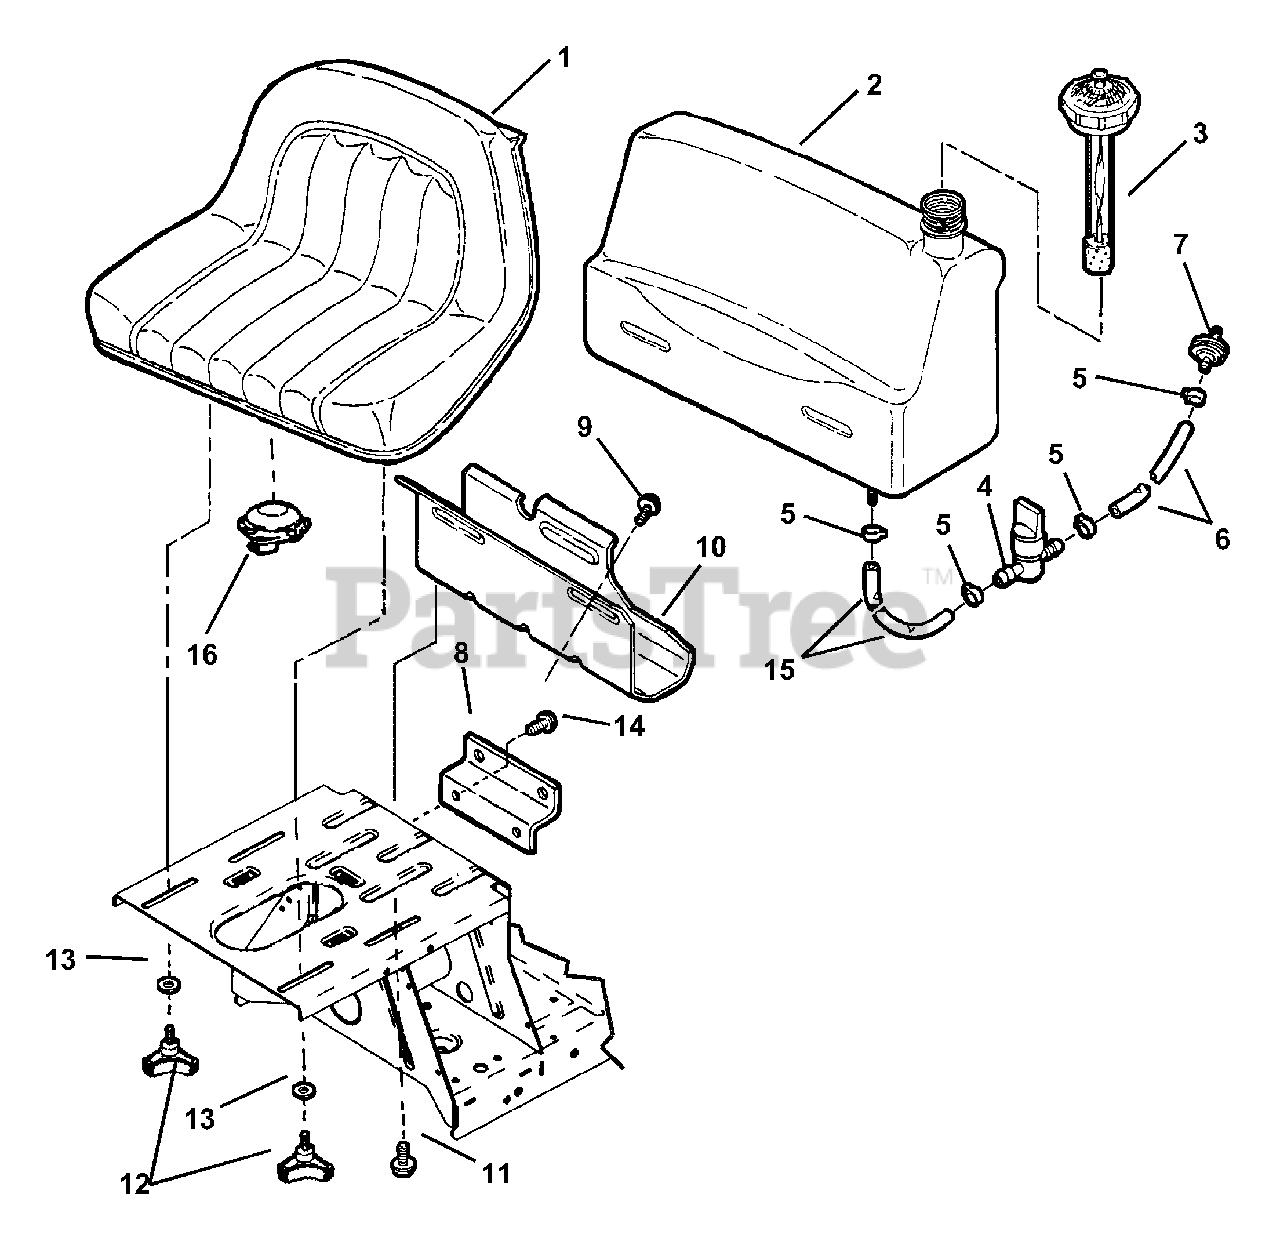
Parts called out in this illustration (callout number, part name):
1	SEAT, Operator (DeLuxe Back)
2	ASSEMBLY, Fuel Tank
3	CAP, Fuel Tank (With Gauge)
4	VALVE, Fuel Shut-Off
5	CLAMP, Fuel Line
6	HOSE, Fuel (5" Long)
7	FILTER, Fuel (In-Line)
8	BRACKET, Tank
9	SCREW, 5/16-18 x 5/8" Self-Tap
10	BRACKET, Fuel Tank (Rear)
11	BOLT, 5/16-18 x 1/2" Hex Fl. Lock
12	KNOB, Seat Adjusting
13	SPACER, 5/16"
14	SCREW, 5/16-18 x 1/2" Hex Self-Tap
15	HOSE, Fuel (24-1/4" Long)
16	SWITCH, Seat (Normally Closed)
